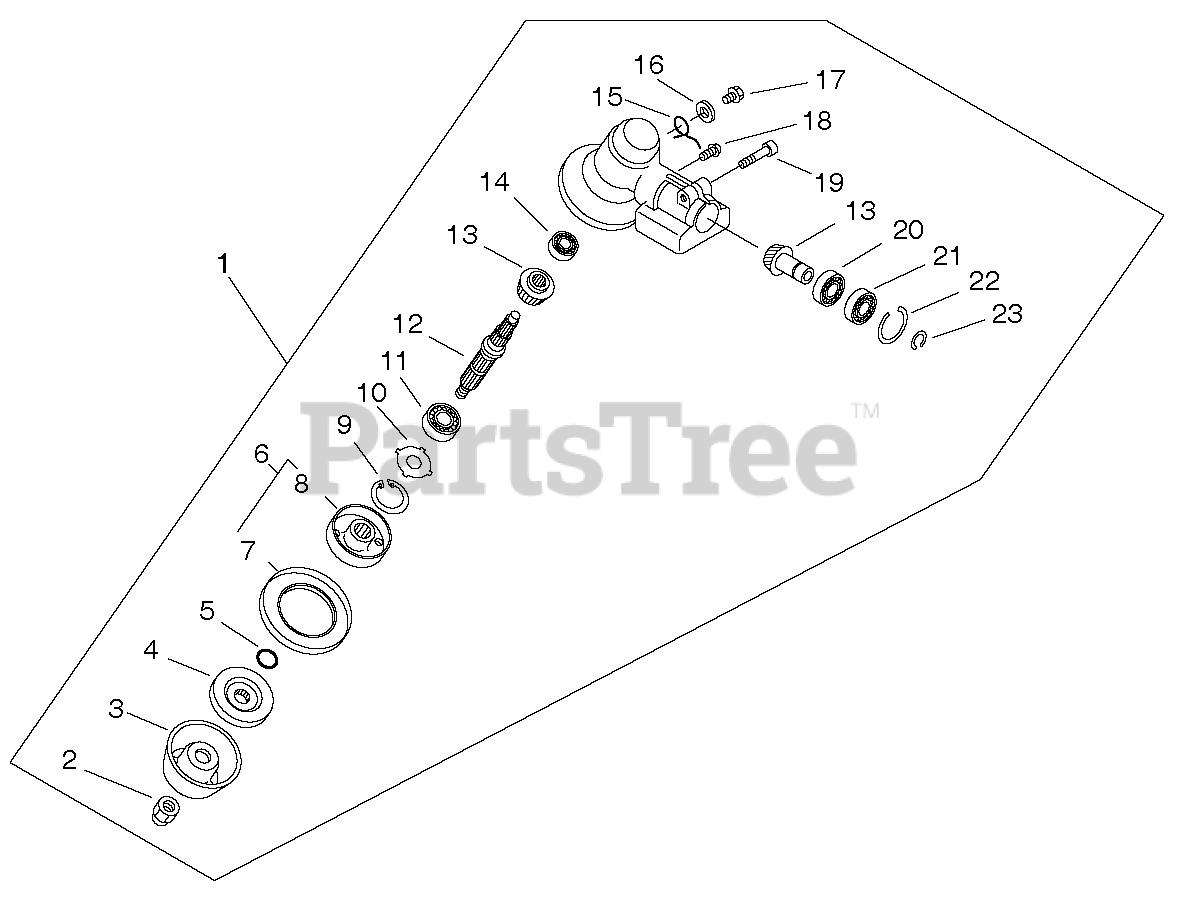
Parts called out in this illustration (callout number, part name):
1	CASE, GEAR
2	NUT, LOCK 10 - NYLON INSERT
4	PLATE, ADAPTOR - LOWER
5	O-RING 12 MM
6	RETAINER ASSY, BLADE
7	PLATE, ADAPTOR - LOWER
8	PLATE, ADAPTOR
9	RING, SNAP Ø32
11	BEARING, BALL 6201
12	SHAFT, GEAR
13	GEAR SET
14	BEARING, BALL 629
15	SPRING, TORSION
16	WASHER 8.5×18×0.8T
17	BOLT M8×8
18	SCREW 5×10
19	BOLT 6×30
20	BEARING, BALL 6001
21	BEARING, BALL 6001Z
22	RING, SNAP 28
23	RING, RETAINING - 12
